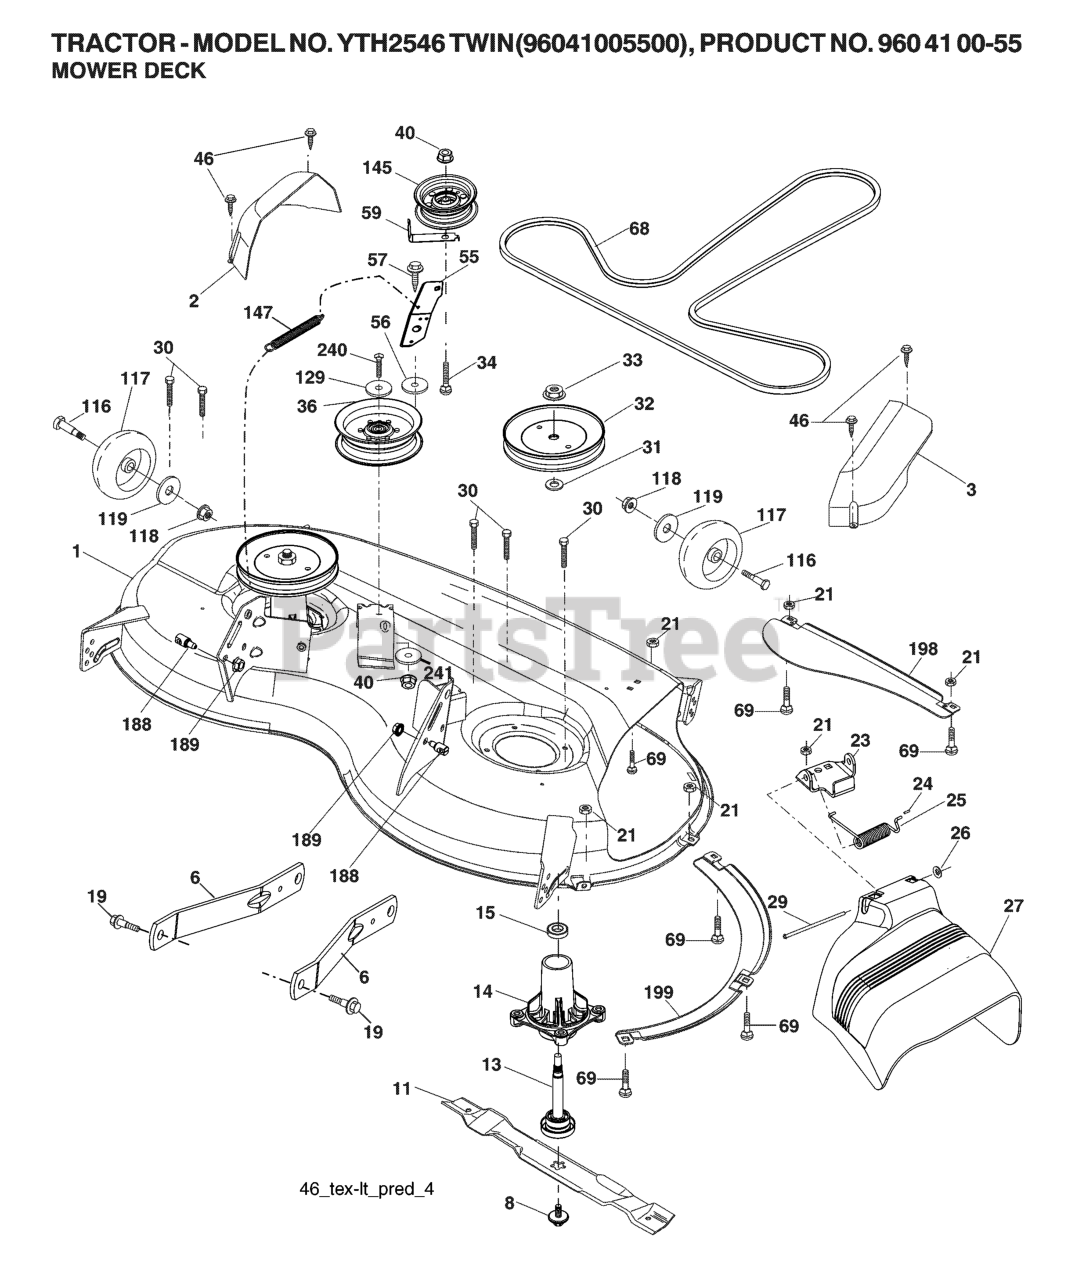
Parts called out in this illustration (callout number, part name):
1	MOWER HOUSING
2	COVER.MANDREL.LH.46"
3	COVER.MANDREL.RH.46"
6	ARM.SUSPENSION.MOWER.R
8	BOLT.WASHER.ASM.7/16-2
11	BLADE.MOWER.46".HI.LIFT
13	SHAFT.ASM.MDRL.N/GREASE.38
14	RP.HOUSING.MANDREL.4PT.
19	BOLT.SHOULDER
21	LOCKNUT
23	BRKT.DEFLECTOR.38"2005+
24	CAP-SLEEVE LT
25	SPRING.TORSION.DEFLECT
26	NUT PUSH M
27	SHIELD.DEFLECTOR.MOWER.46"BLAC
29	ROD.HINGE
30	SCREW, WASHER HEAD
31	WASHER.SPACER.MANDREL
32	PULLEY.MANDREL.5.438.P
33	NUT.FLANGE.LOCK.TOP
34	BOLT.3/8-16X1.50
36	PULLEY.IDLER.2006
40	NUT LOCK FLG 3/8-16 UNC
46	SCREW.1/4-20X5/8
56	SPACER.RETAINER
57	SCREW 3/8-16X1
59	GUARD, BELT
68	V-BELT
69	BOLT
116	BOLT.SHOULDER.3/8-16X3-5/8.
117	RP WHEEL. GUAGE RALLY
118	NUT LOCK FLG 3/8-16 UNC
119	WASHER
129	WASHER
145	PULLEY.IDLER.FLAT
147	SPRING.MOWER.DRIVE.ELECTRIC
188	STUD.FASTNER.W/ANTI-ROTATE
189	NUT LOCK HEX FLANGE 5/16-18
198	BAFFLE CENTER FRONT
199	BAFFLE FRONT RH
240	BOLT-HEX EAK
241	WASHER 12/32X2X10GA
